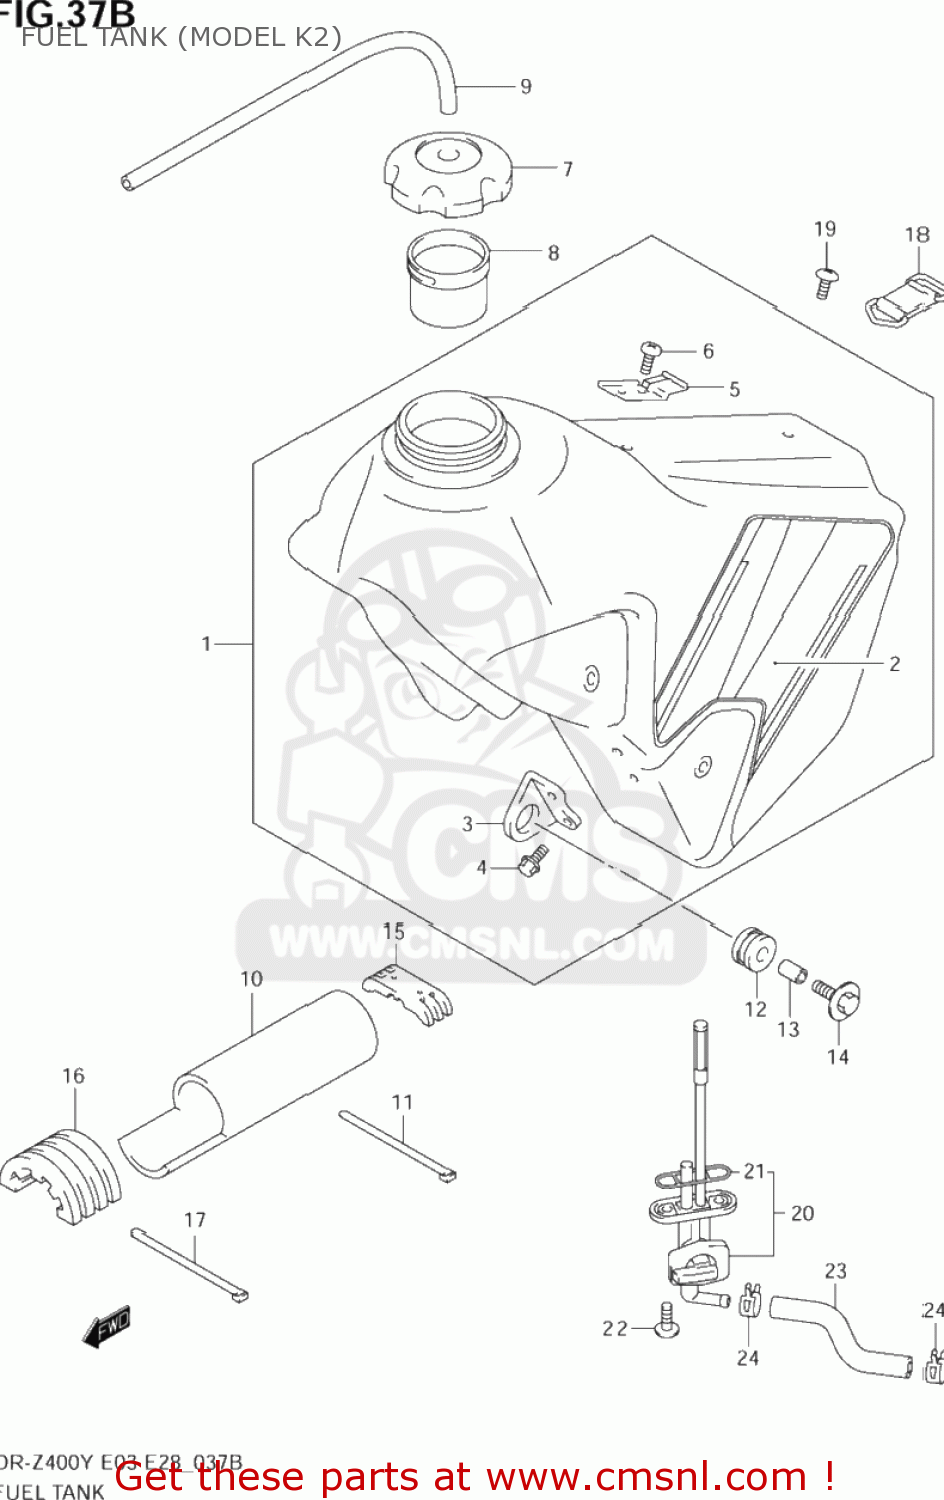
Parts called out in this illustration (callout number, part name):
1	FUEL TANK ASSY
2	TAPE SET,FUEL TANK
3	BRACKET,FUEL TANK FR
4	BOLT
5	HOOK,SEAT FR
6	SCREW 6X12
7	CAP ASSY,FUEL TANK FILLER
8	TUBE,FILLER INLET
9	HOSE(5X8.2X600)
10	SHIELD,FUEL TANK
11	CLAMP(L:300)
12	CUSHION,MUFFLER
13	SPACER(6.5X9X13.5)
14	BOLT(6X30)
15	CUSHION,FUEL TANK RR
16	CUSHION,FUEL TANK
17	CLAMP(L:300)
18	BAND,FUEL TANK RR
19	SCREW
20	COCK ASSY,FUEL
21	GASKET,JOINT (NAS)
22	BOLT
23	HOSE,FUEL
24	CLIP
